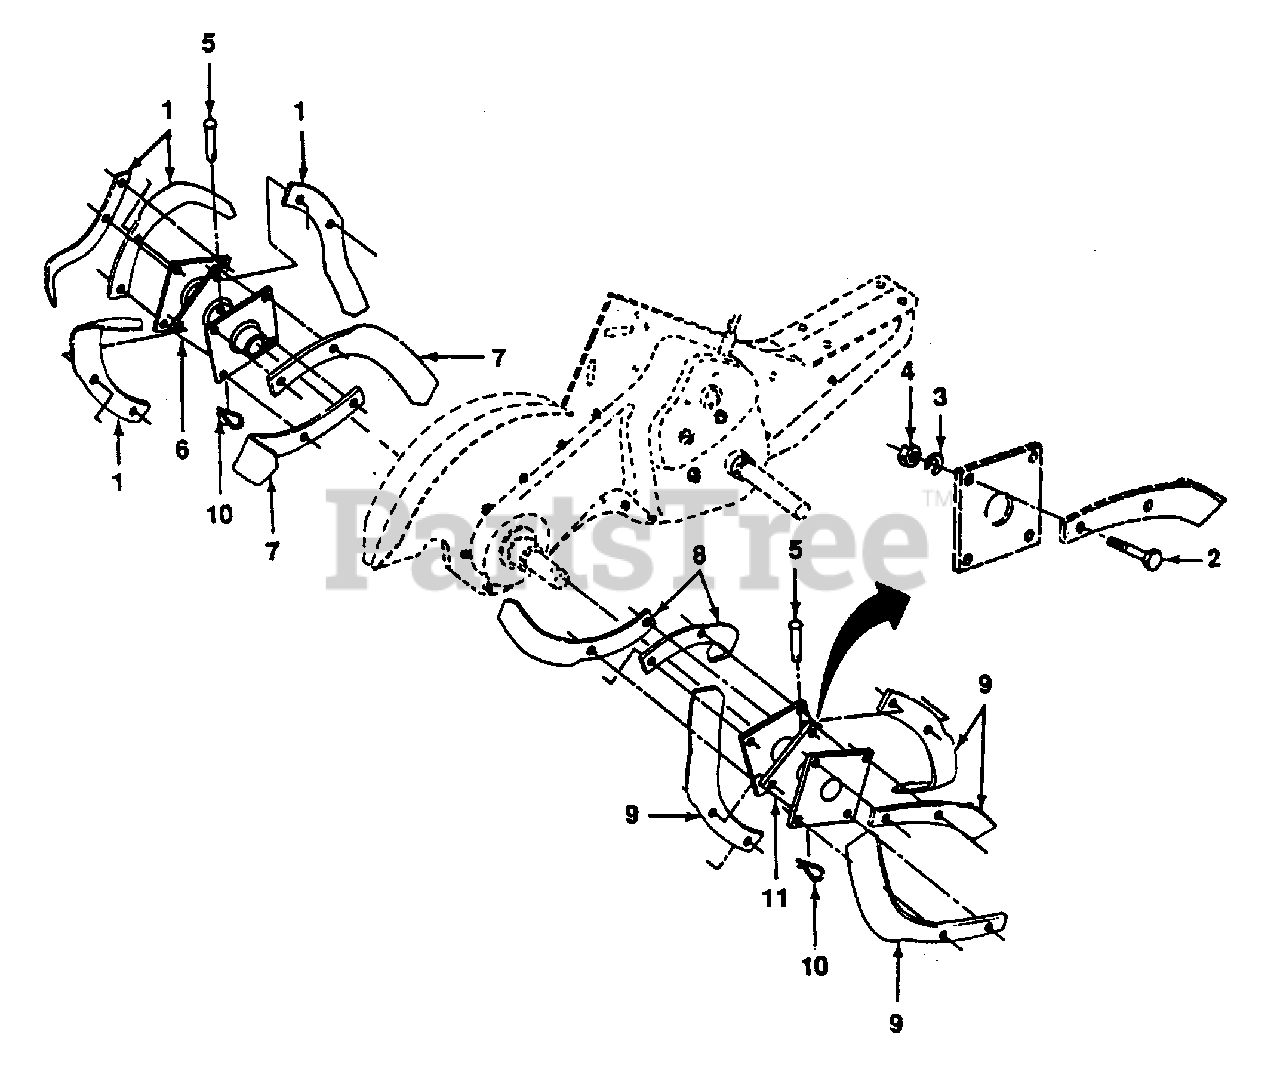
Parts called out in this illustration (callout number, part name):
1	Tine, L. H. Outer (AYP part number)
2	Bolt, Hex 3/8-24 x 1 (AYP part number)
3	Washer, Lock 3/8 (AYP part number)
4	Nut, Hex 3/8-24 (AYP part number)
5	Pin, Clevis
6	Assembly, Hub and Plate L. H. (AYP part number)
7	Tine, L. H. Inner (AYP part number)
8	Tine, R. H. Inner (AYP part number)
9	Tine, R. H. Outer (AYP part number)
10	Clip, Hairpin (AYP part number)
11	Assembly, Hub and Plate R. H. (AYP part number)
